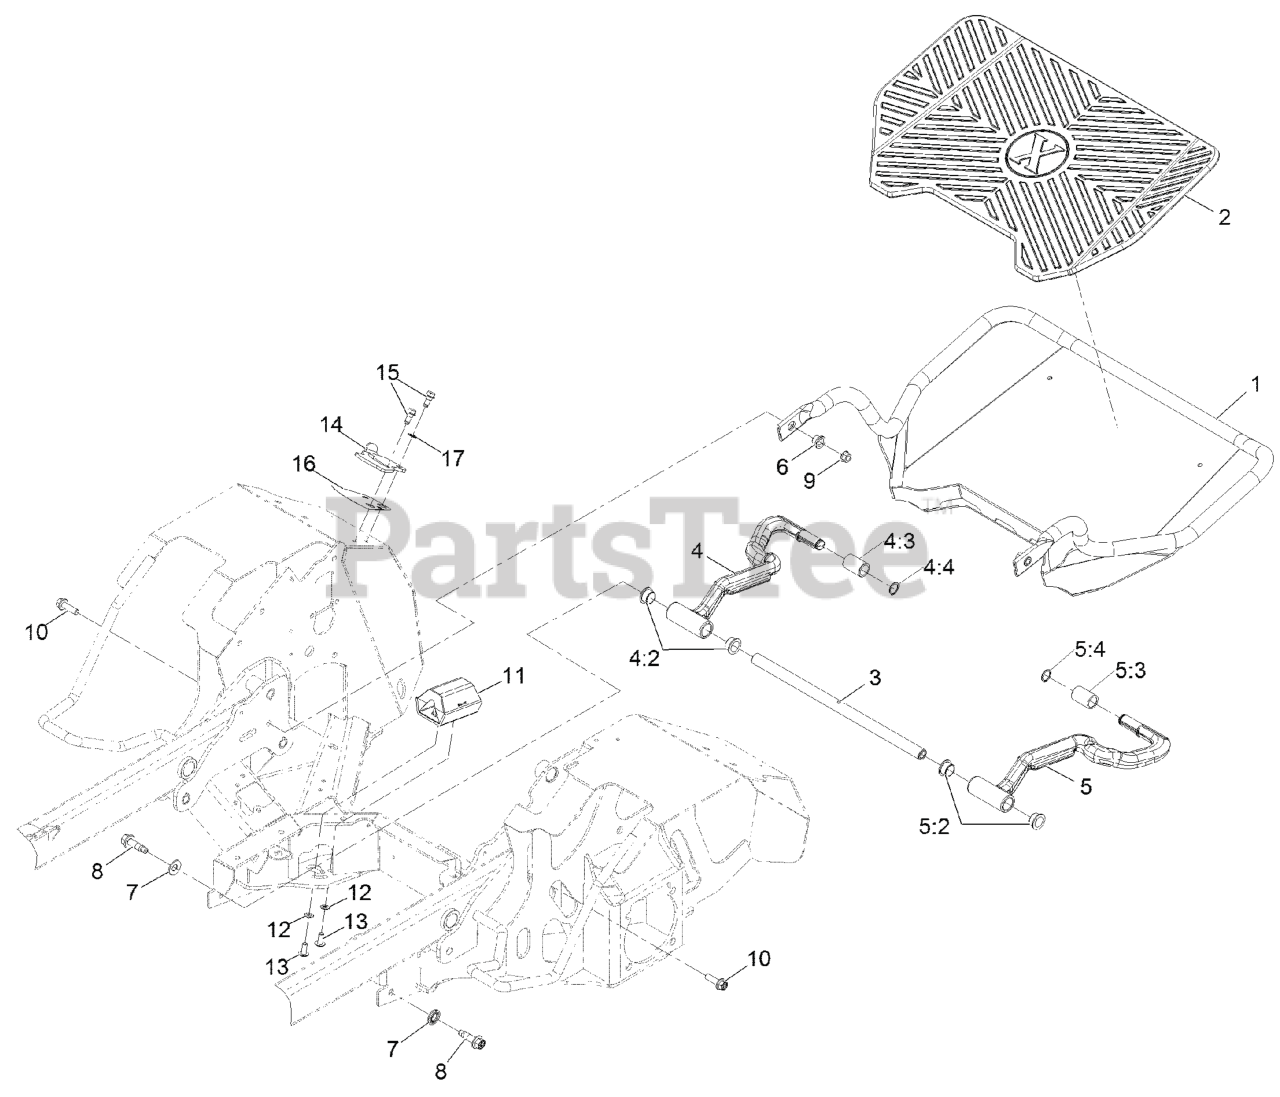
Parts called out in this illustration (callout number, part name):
1	WELD, PLATFORM
2	MAT, PLATFORM
3	SHAFT, CROSS
4	ASM, RT ARM W/ BUSHINGS
4:2	BUSHING-FLANGE
4:3	Bushing, Sleeve
4:4	RING-SNAP
5	ASM, LT ARM W/ BUSHINGS
5:2	BUSHING-FLANGE
5:3	Bushing, Sleeve
5:4	RING-SNAP
6	BUSHING-FLANGED
7	WASHER-SPRING
8	SCREW-HHF
10	SCREW, HHF
12	WASHER-LOCK
13	SCREW-TORX
14	LATCH, PLATFORM
15	SCREW-SHOULDER
16	DECAL-LATCH LOCK
17	WASHER, PLASTIC
17	Washer, Wave
